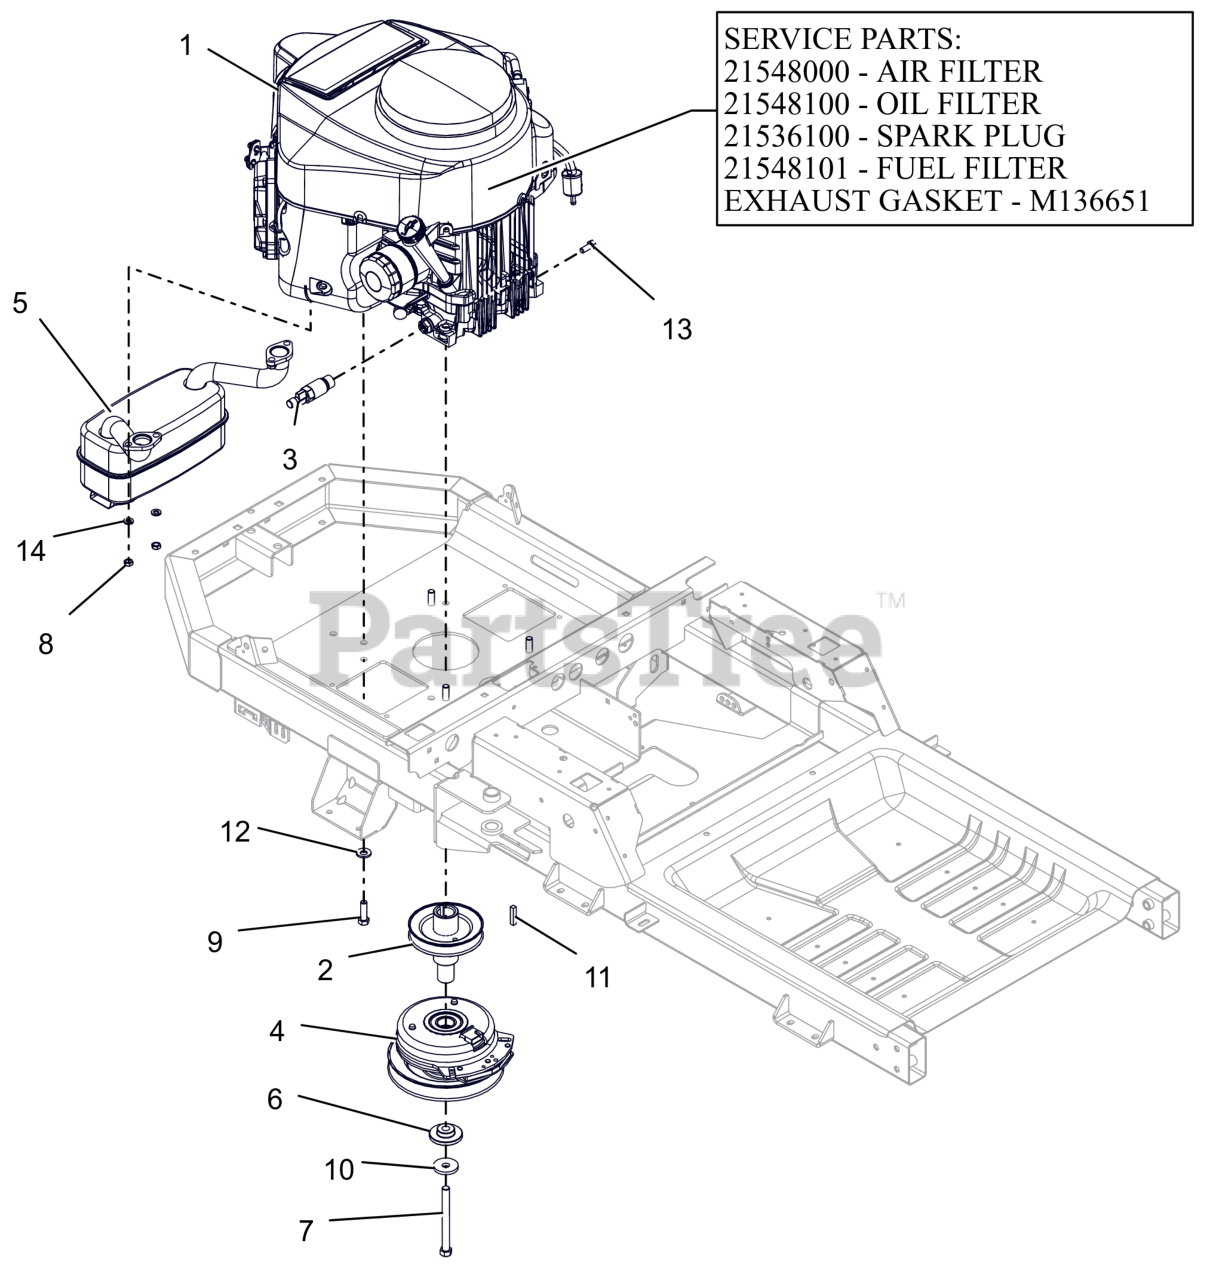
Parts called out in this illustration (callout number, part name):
1	ENGINE, KAWASAKI FR691 23HP
1	AIR FILTER, KAWASAKI FR
1	OIL FILTER, KAWASAKI FR
1	PLUG, SPARK
1	FUEL FILTER-KAWASAKI FR
1	GASKET, MUFFLER #
2	WLDMT, DRIVE SHEAVE-X
3	DRAIN, OIL M20X2.5
4	CLUTCH,105FTLB MONOPOLE 6.83"
5	MUFFLER - KAWASAKI
6	BSHG-FLG .469X1.06X.574X2.0
7	BLT, HEX .44-20X4.50 G8 ZCC NT
8	NUT, LK-CTR-JAM M8-1.25 GR8.8 ZC120
9	BLT, HEX .38-16X1.25 G5 ZCC NT
10	WASHER, 7/16" SPRING DISK
11	KEY-SQ .25 X 1.25 X .25 SAE
12	WASHER, 3/8" SPRING DISC
13	BLT, HEX M8-1.25X20 G8.8 ZCC
14	WSHR,LK-REG .312X.078 ZCC
